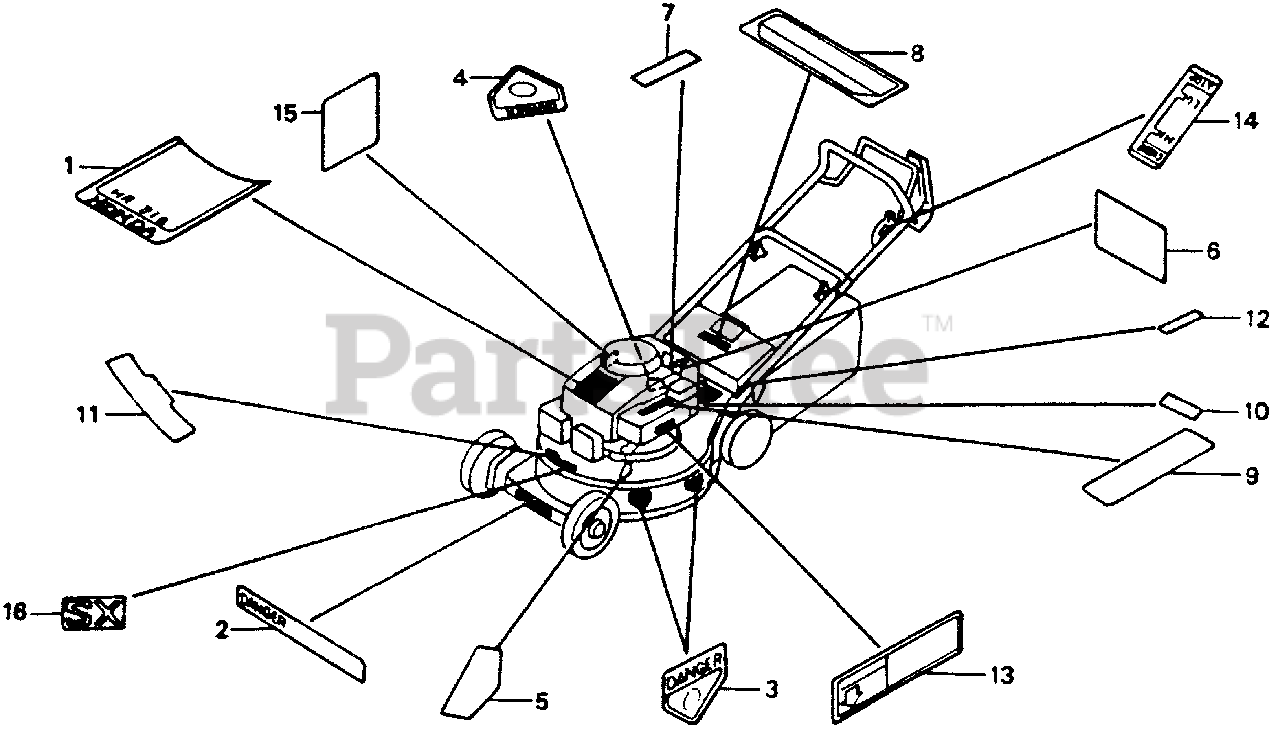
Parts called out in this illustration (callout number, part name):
1	EMBLEM, TOP (NOT AVAILABLE)
2	LABEL A, HOUSING CAUTION (ENGLISH)
3	CAUTION B, HOUSING
3	LABEL C, HOUSING CAUTION
4	LABEL B, HOUSING CAUTION
4	LABEL C, HOUSING CAUTION
5	LABEL, STEP POSITION (ENGLISH)
6	CAUTION, OPERATOR (ENGLISH)
7	LABEL, FUEL CAUTION (ENGLISH)
8	LABEL, DISCHARGE GUARD CAUTION (ENGLISH) (NOT AVAILABLE)
9	MARK, EASY START (ENGLISH)
10	LABEL, CHANGE INDICATION
11	LABEL, PLUG CAUTION
12	MARK, HANDLE ADJUST (ENGLISH) (NOT AVAILABLE)
13	LABEL, AIR CLEANER CAUTION (H)
14	MARK, THROTTLE (ENGLISH)
15	MARK, OIL CAUTION
16	MARK, TYPE (SX)
